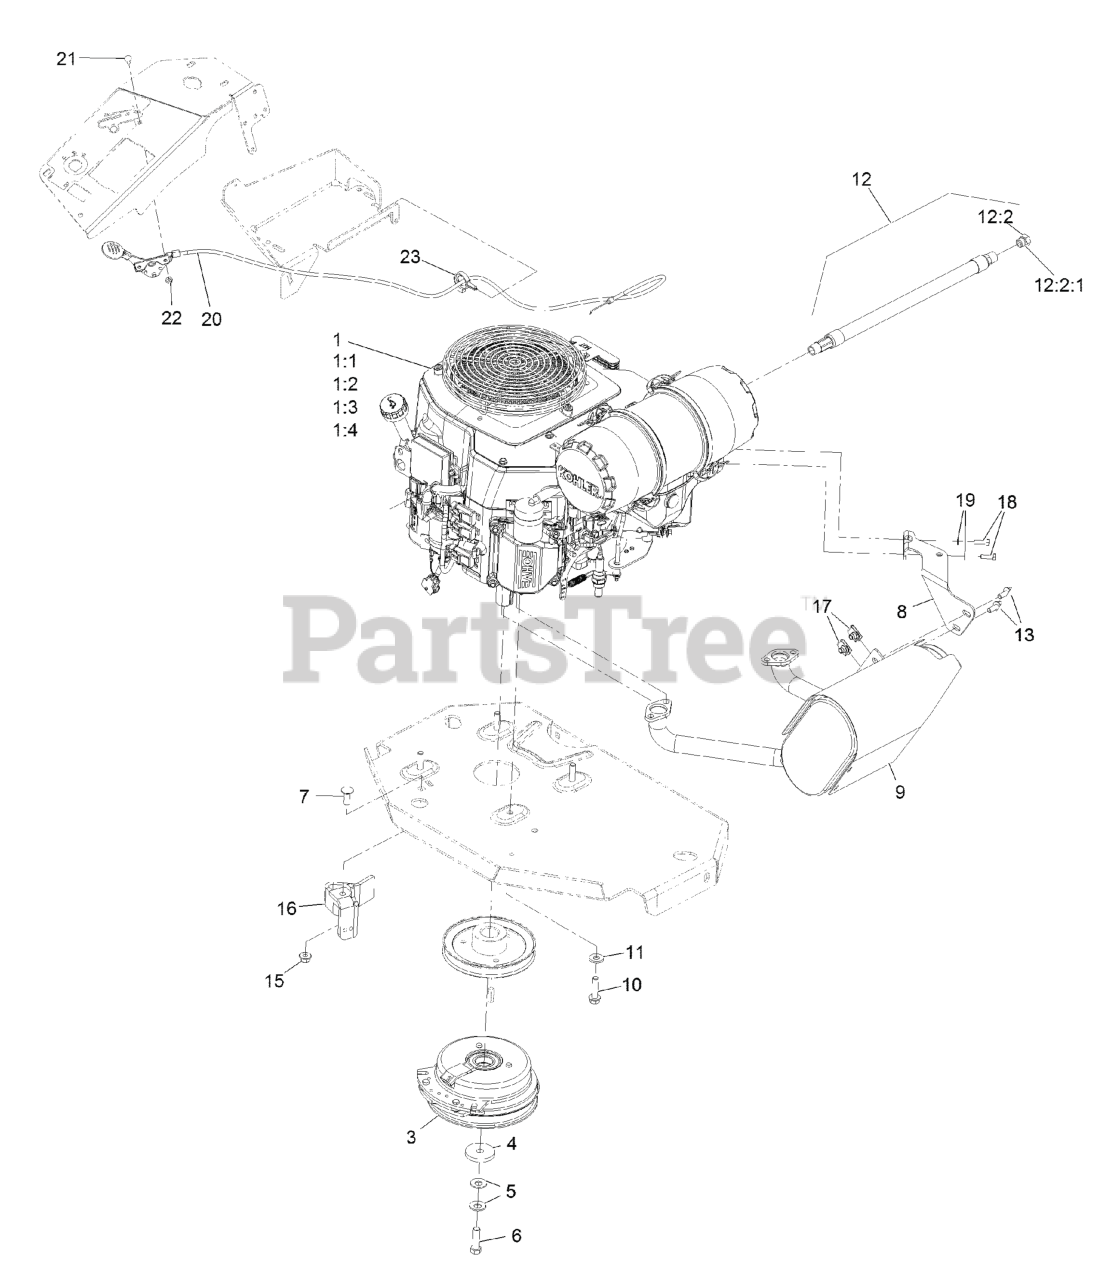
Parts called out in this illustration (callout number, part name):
1:1	Kohler 52 050 02-S Engine Oil Filter
1:2	Kohler 25 083 01-S Engine Air Filter
1:3	Kohler 25 083 04-S Safety Filter
1:4	Kohler 25 050 50-S Propane Fuel Filter
3	CLUTCH KIT
4	WASHER-CLUTCH
5	WASHER-SPRING
6	SCREW-HH 7/16-20 X 1 1/2 W/LOCTITE
7	SCREW-CARR
8	MUFFLER BRACKET KIT
9	MUFFLER KIT
10	SCREW-HWH
11	WASHER-BELLEVILLE
12	OIL DRAIN HOSE ASM
12:2	PLUG-HH
12:2:1	O-RING
13	SCREW-HHF
15	NUT-HF, NI
16	CLUTCH-ANCHOR
18	SCREW-HH M6-1 X 20Mm W/Patch
19	WASHER-SPRING
20	ASM,THROTTLE CABLE
21	BOLT-CARR
22	NUT-LOCK, NI
23	CLAMP-HOSE
